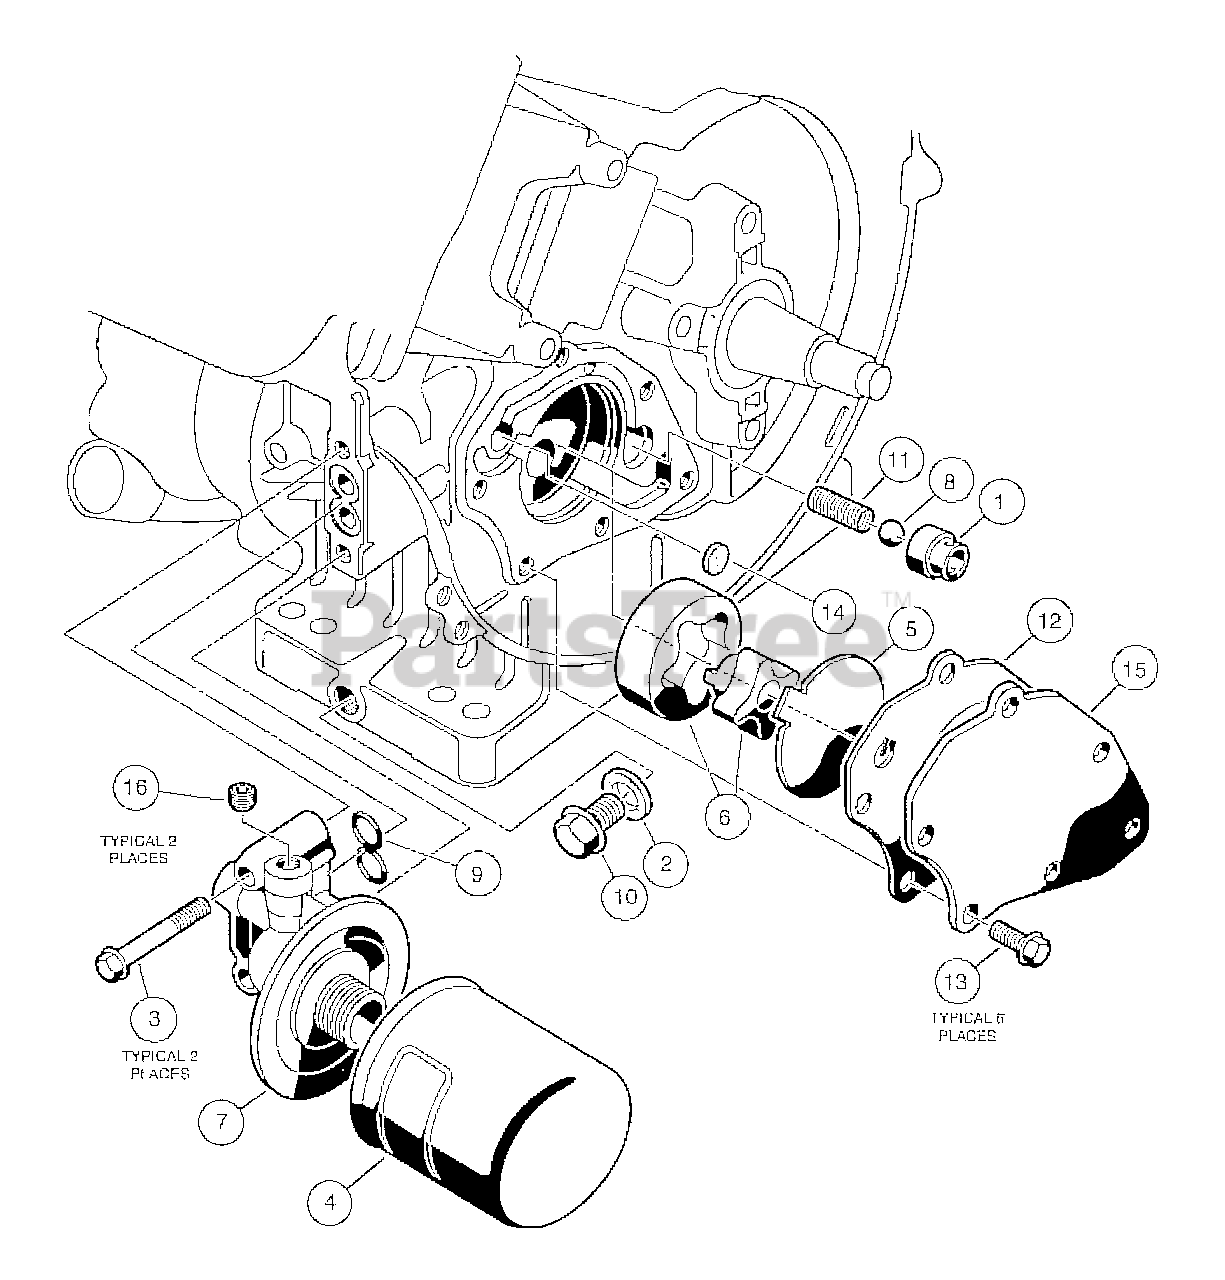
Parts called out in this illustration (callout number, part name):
1	Seat, Value Oil Press Relief
2	Gasket, Drain Plug
3	Bolt, Flange Head
4	Filter, Oil
5	Plate, Oil Pump
6	Oil Pump And Rotor
7	Bracket, Oil Filter Mount
8	Ball, Steel, Press, Relief
10	Plug. Drain
13	Bolt, Flanged
15	Cover, Pump
